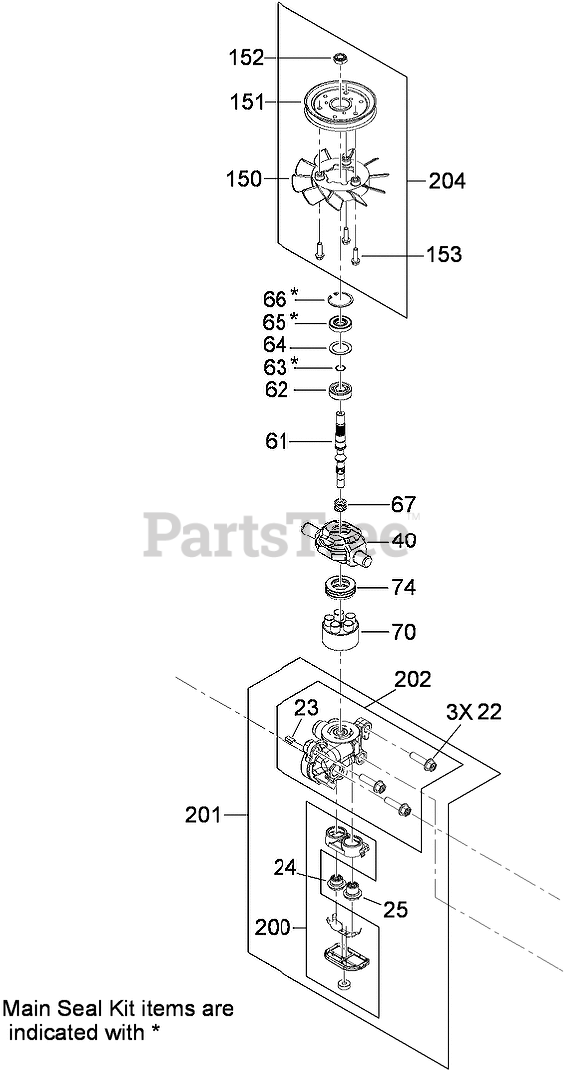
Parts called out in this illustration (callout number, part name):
22	SCREW-HFHC
23	PLATE-BYPASS
24	CHECK PLUG ASM
25	CHECK PLUG ASM
40	TRUNNION-PLATE, SWASH
61	SHAFT-INPUT
62	BEARING-BALL
63	RING-RETAINING, WIRE
64	SPACER
65	SEAL-LIP
66	RING-RETAINING
67	SPRING-HELICAL
70	CYLINDER BLOCK KIT
74	BEARING-THRUST, BALL
150	FAN
151	PULLEY ASM
152	NUT-LOCK
200	FILTER KIT
201	CENTER SECTION KIT
202	CENTER SECTION KIT
204	FAN PULLEY KIT
